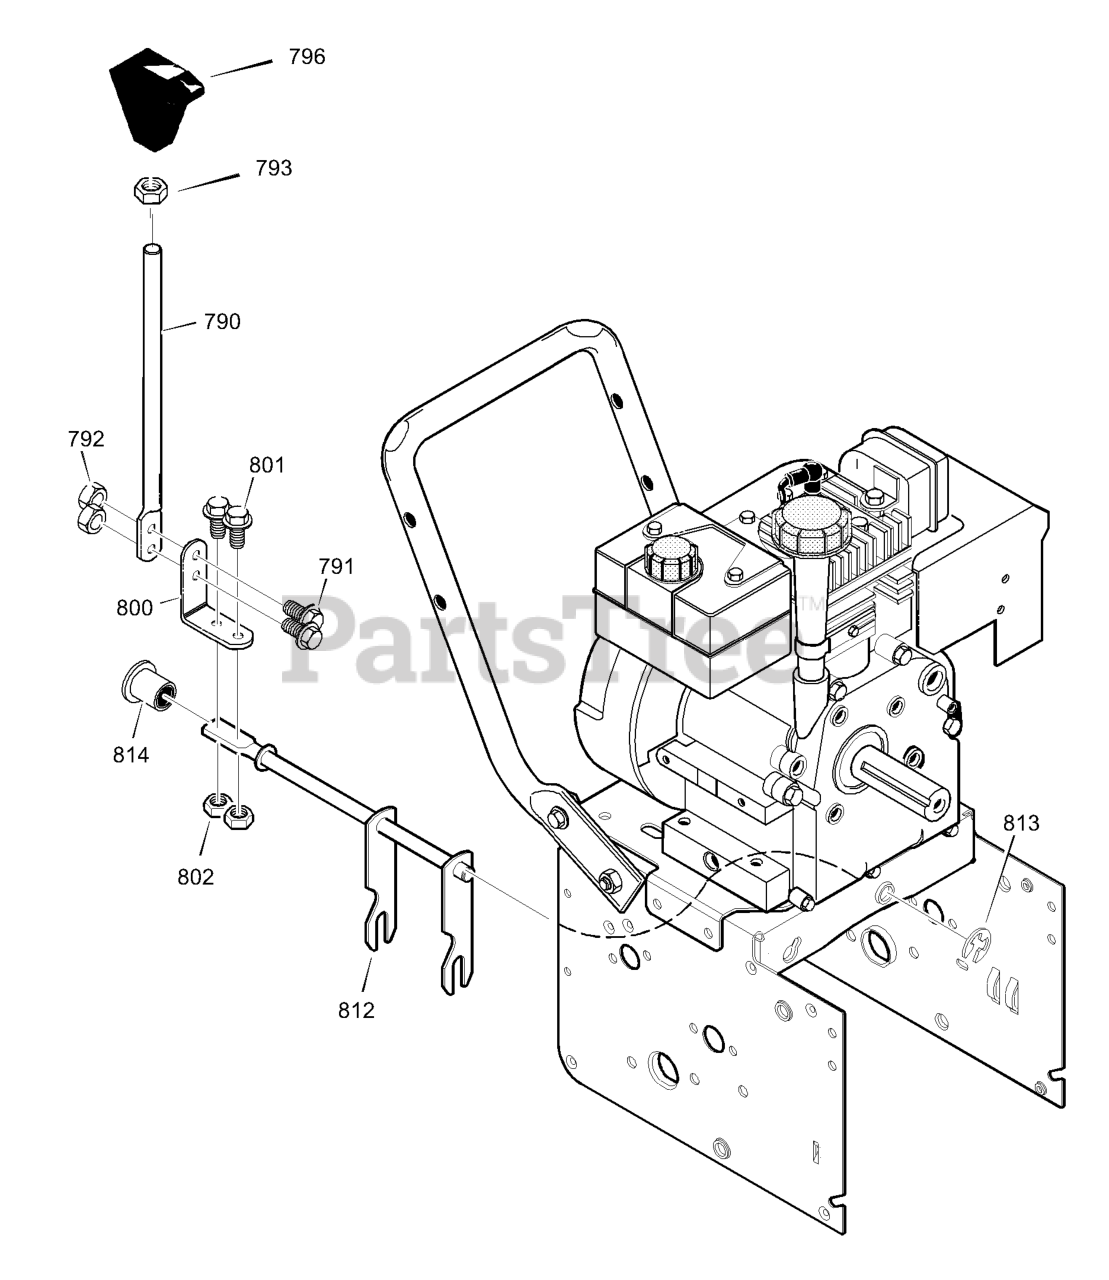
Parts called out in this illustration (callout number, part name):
790	ROD, SHIFT
791	SCREW, 1/4-20X.75
792	NUT, 1/4-20
793	NUT, 1/2-13 JAM
796	KNOB, SLIP
800	LEVER, SPRING
801	SCREW, 1/4-20X.75
802	NUT, 1/4-20
811	BEARING, FLANGED
812	ROD ASSY., SPEED SELECT
813	RETAINER, RING
